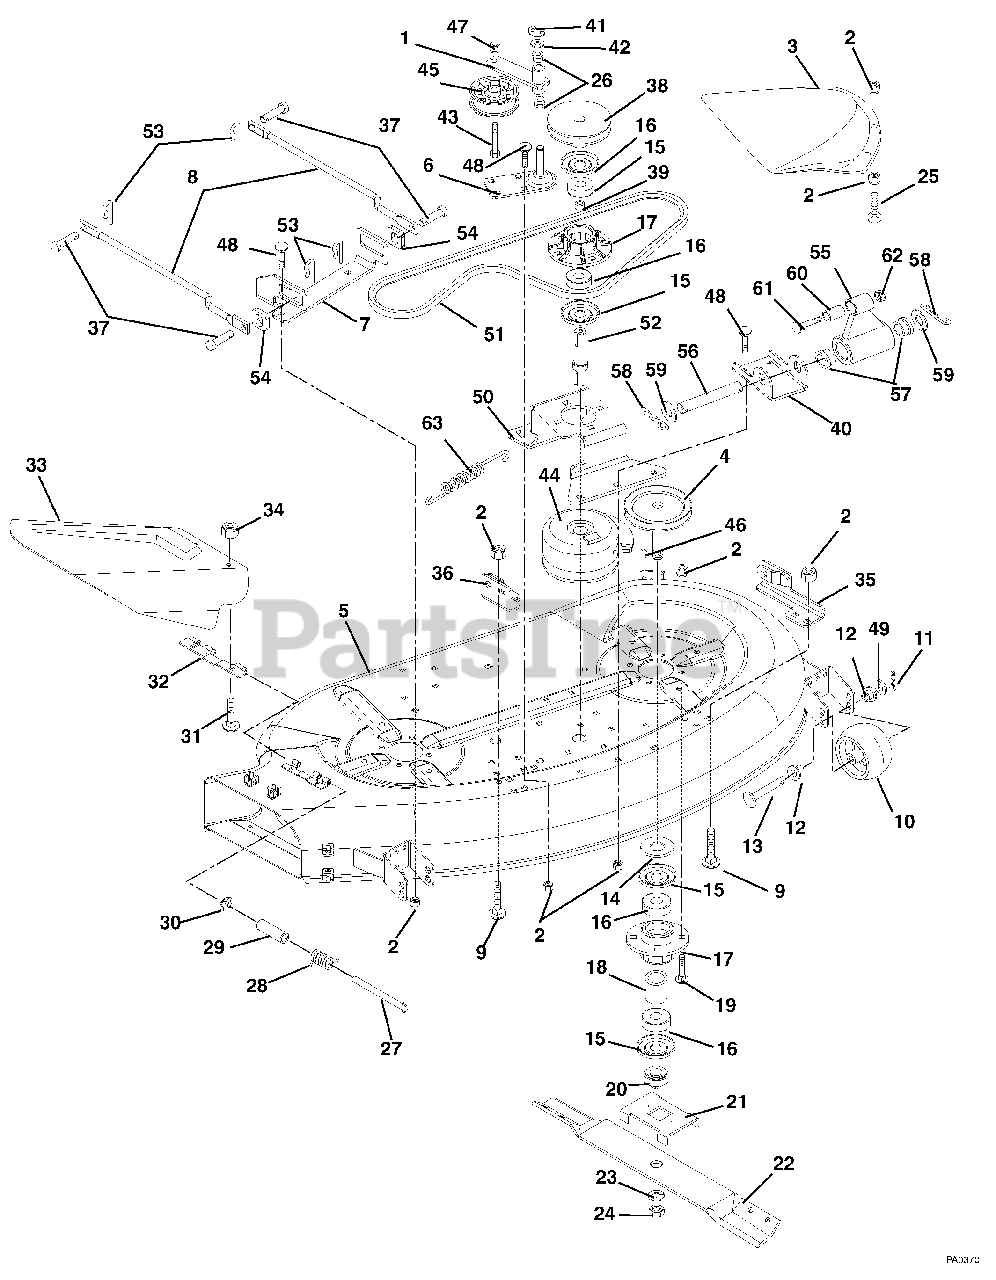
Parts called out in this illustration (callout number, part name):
1	Weldment, Idler
2	Nut, Locking Top Flange .38-16
4	Sheave, Left Spindle
4	Sheave, Right Spindle
5	Deck, 40"
6	Bracket, Idler Mount
7	Bracket, Rear Hanger
8	Link, Stabilizer 40" Deck
9	Bolt, Round Head Square Neck .38-16 x .75 Grade 5
10	Roller
11	Pin, Hair Internal .08 x .18 x 1.18
12	Bushing, Flange .372 x .500 x .312 x .625
13	Clevis Pin .368/.373 x 3.25
14	Washer, Flat Steel .755 x 1.25 x .125
15	Bearing Slinger
16	Bearing, Ball .750 x 1.781 x .61
17	Spindle Housing
18	Spacer .751 x 1.00 x 1.14
19	Bolt, Round Head Square Neck .38-16 x 1.0 Grade 5
20	Retainer Hub
21	Blade Tray 48
23	Washer, Lock .75 x .188
24	Nut, Jam .75-10
25	Bolt, Hex .38-16 x 1.00 Grade 5
26	Bushing, Flange .500 x .625 x .312 x .75
28	Spring-Torsion .090 x .37 x .63
29	Bushing
30	Ring, Retaining External .313 x .025
31	Bolt, Round Head Square Neck .25-20 x .50
32	Hinge Plate
33	40 In Deflector
34	Nut, Locking Flange .25-20
35	Bracket, Deck Link Left Hand
36	Bracket, Deck Link Right Hand
37	Pin, Clevis .494 x 1.00
38	Pulley, 40" Deck Input
39	Spacer .75 x 1.00 x 1.14
40	Bracket, Front Hanger
41	Ring, Retaining External .50 x .042
42	Washer, Flat Steel .505 x .880 x .072
43	Bolt, Hex .38-16 x 1.50 Grade 5
44	Electric Clutch/Brake
45	Idler, Flat 3.00 x .38
46	Key, Woodruff .188 x .625 x .31
47	Nut, Locking Center .375-16
48	Bolt, Round Head Square Neck .31-18 x .75 Grade 5
49	Bolt, Round Head Square Neck .31-18 x 1.00
50	Bracket, Spindle Housing Mount
51	V-Belt (38.37)
52	Input Shaft 40" Deck
53	Clip, Spring
54	Slider, Hanger Bracket
55	Link, Front Lift
56	Pivot, Front Lift Lower
57	Bushing, 1.00 x .75 x 1.00
58	Pin, Hair
59	Washer, Flat Steel .75 x 1.47 x .134
60	Bushing, Sleeve .50 x .75 x 1.56
61	Bolt, Round Head Square Neck .50-13 x 2.75
62	Nut, Locking Center Jam .50-13
63	Spring-Tension .095 x .50 x 5.5
